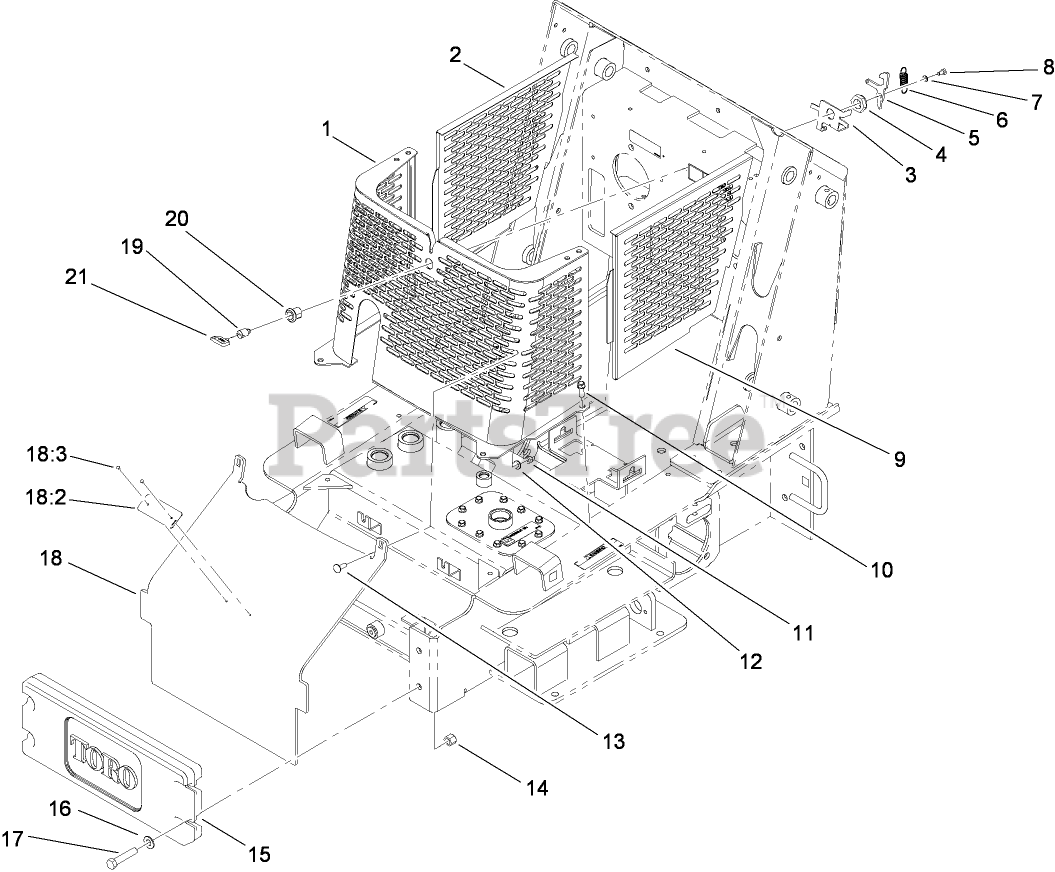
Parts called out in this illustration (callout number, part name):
1	GRILL ASM
2	PANEL-SIDE, RH
3	BRACKET-LATCH
4	NUT-LOCK, NI
5	CAM-LATCH
6	SPRING
7	WASHER-LOCK
8	SCREW-HH
9	PANEL-SIDE, LH
10	SCREW-TAPTITE
11	NUT-LOCK, NI
12	WASHER-PLAIN
13	SCREW-CARR
14	NUT-LOCK, NI
15	COUNTERWEIGHT-FRONT
16	WASHER-FLAT
17	SCREW-HH
18	HEAT SHIELD ASM
18:2	PLATE-HOT SURFACE
18:3	RIVET-POP
19	INSERT-LATCH
20	HOUSING-LATCH
21	KEY-LATCH, HOOD
